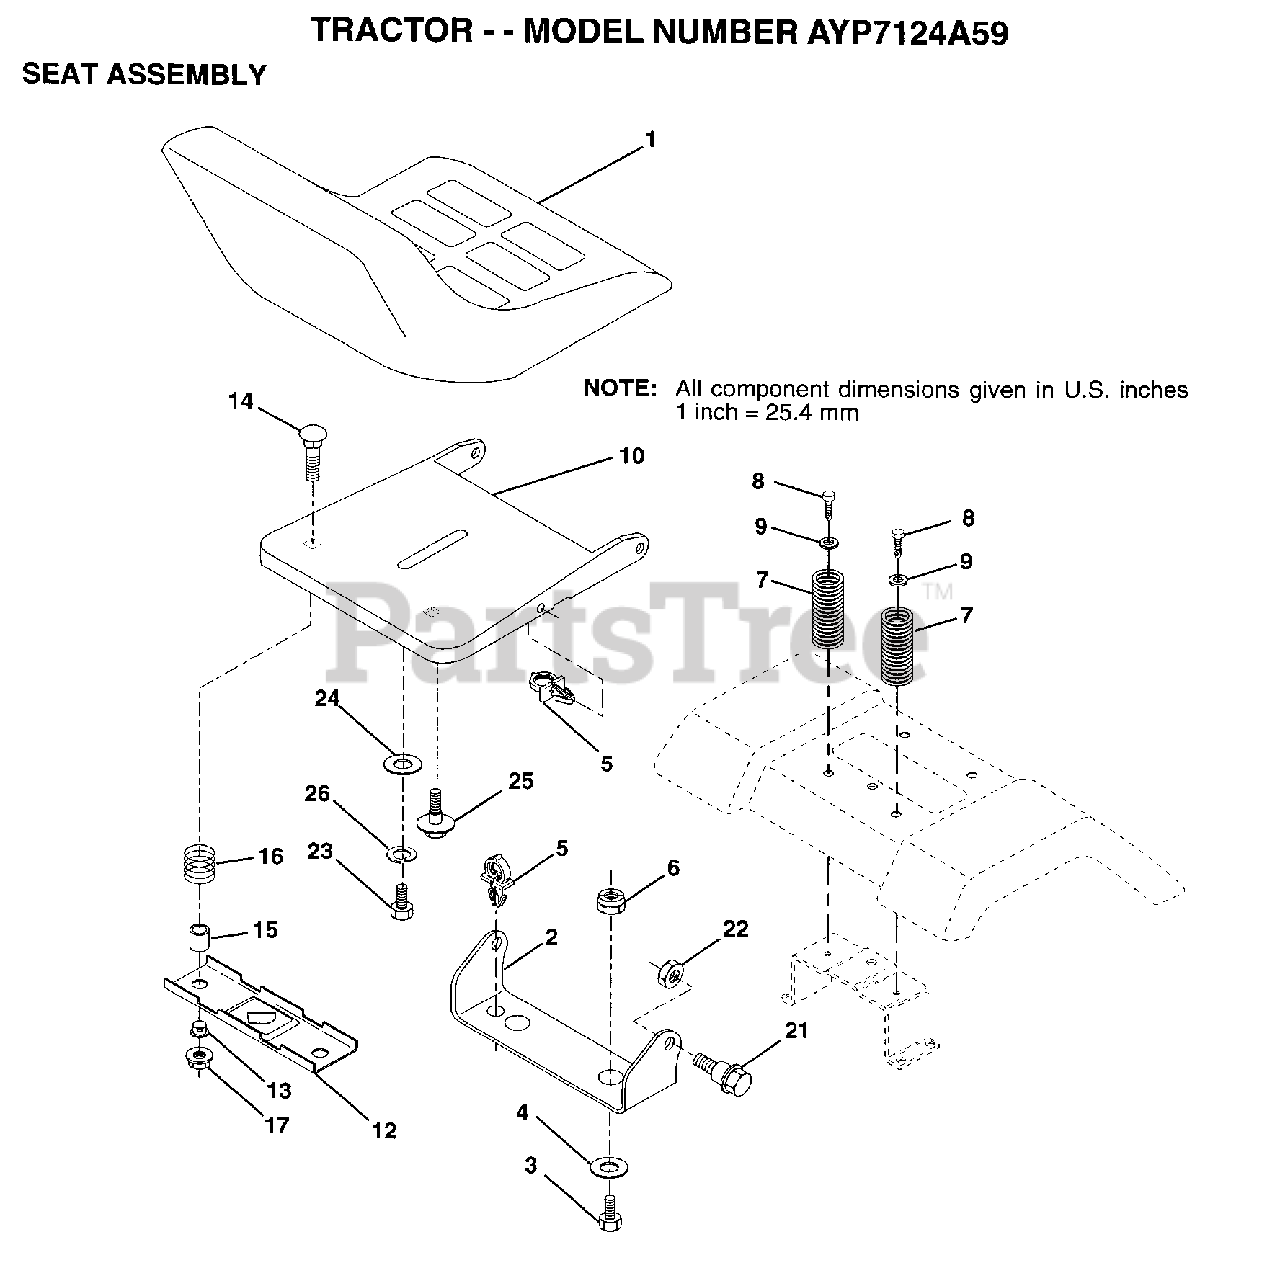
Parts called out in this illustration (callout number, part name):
2	BRACKET PVT SEAT
3	BOLT
4	WASHER PM
5	CLIP.PUSH-IN.HING
6	NUT
7	SPRING COMPRESSIO
8	SCREW GTV
9	WASHER
12	BRKT SWITCH
13	BUSHING
15	SPLIT SPACER
16	SPRING
21	BOLT.SHLD.5/16-18
22	NUT
23	BOLT
24	WASHER
25	"BOLT,SHOULDER"
26	LOCKWASHER
